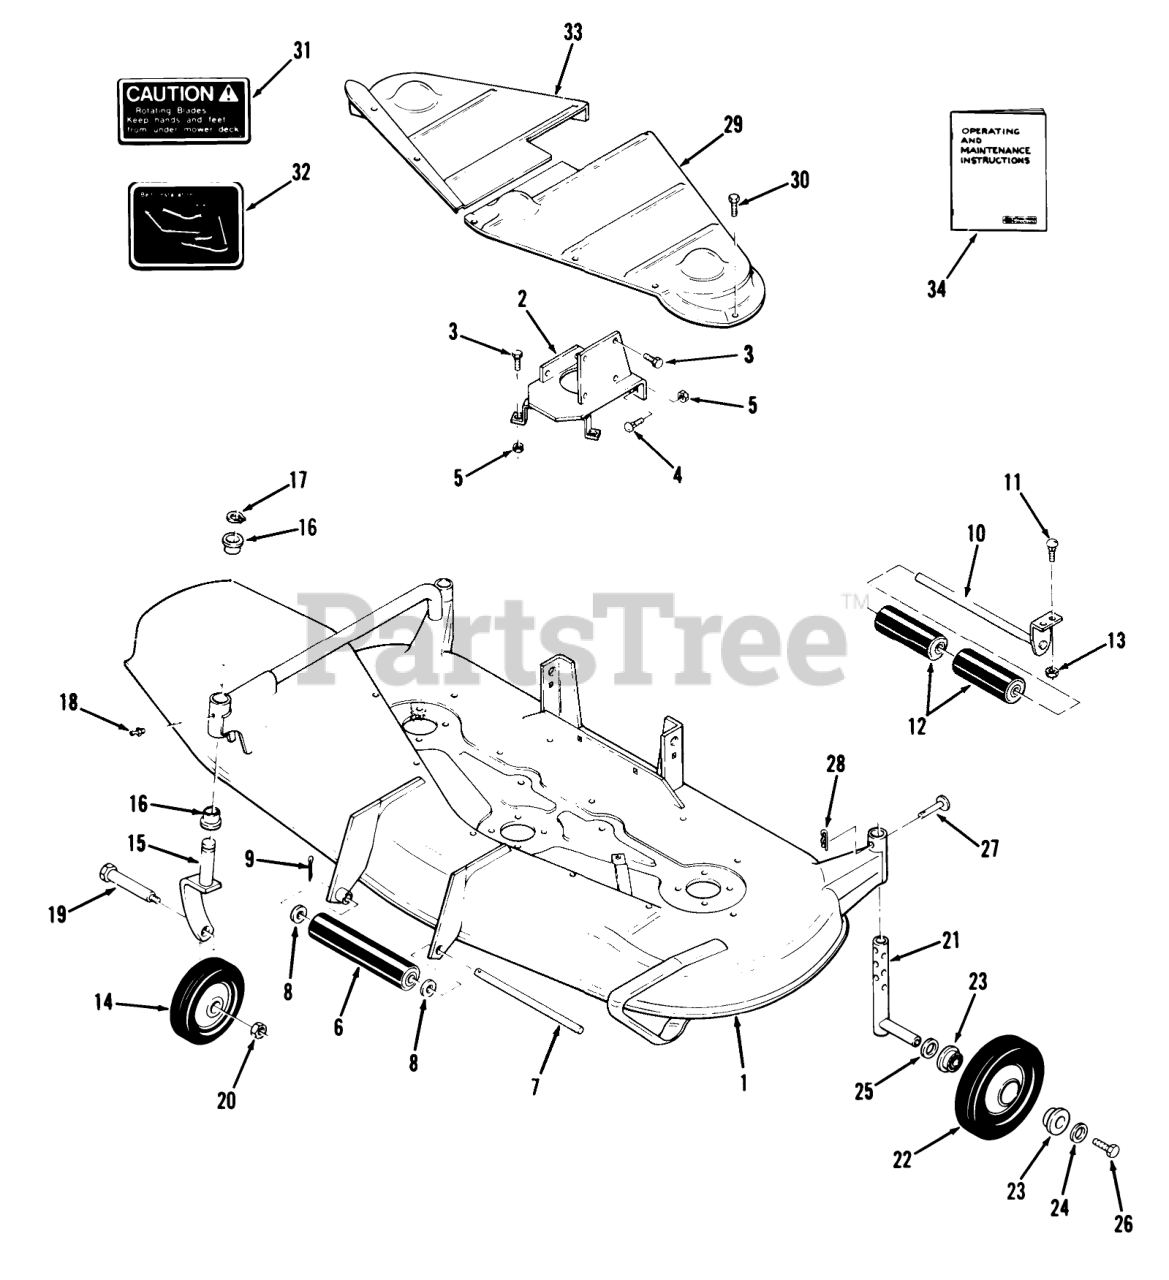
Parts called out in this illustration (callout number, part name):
1	Mower Deck
2	Gear Box Base
3	Bolt
4	Bolt-Carriage
5	Nut
6	ROLLER-FRONT
7	SHAFT-FRONT ROLLER
8	WASHER
9	Cotter Pin5/32 X 2
10	Rear Roller Bracket
11	Bolt
12	Rear Roller, 7"
13	Nut
14	Wheel
15	Caster Arm
16	BEARING
17	RING-SNAP, EXTERNAL
18	Zerk
19	BOLT-SHOULDER
20	Nut
21	Gauge Wheel Arm
22	Gauge Wheel (with Bearings)
23	Ball Bearing
24	Collar
25	WASHER
26	Bolt
27	CLEVIS PIN
28	Hairpin Cotter
29	L.H. Drive Shield
30	Bolt
31	Caution Decal
32	"Belt" Decal
33	R.H. Drive Shield
34	Operating and Maintenance Instructions
